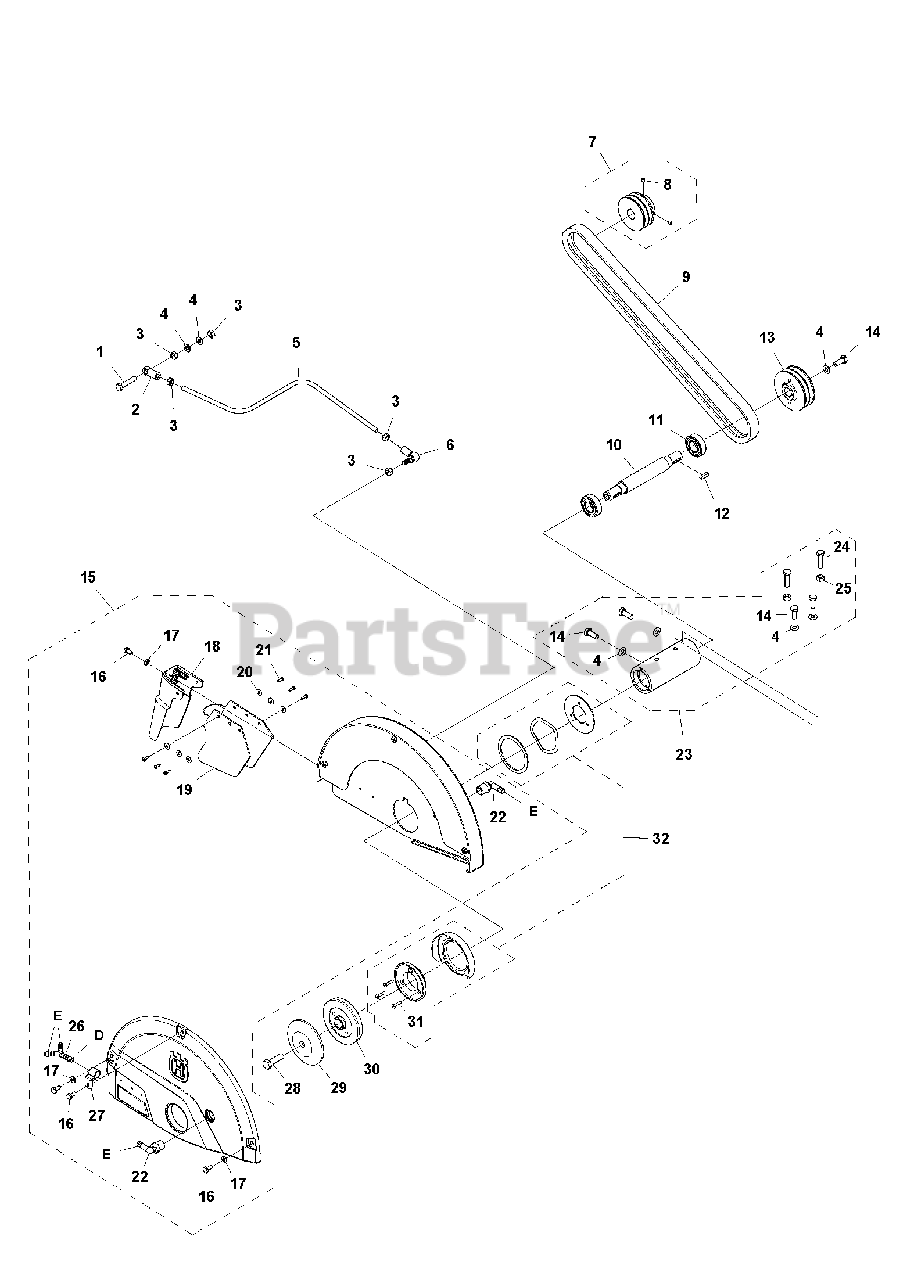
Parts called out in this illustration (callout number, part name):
2	HEXAGON NUT
4	WASHER
11	BALL BEARING
25	HEXAGON NUT
